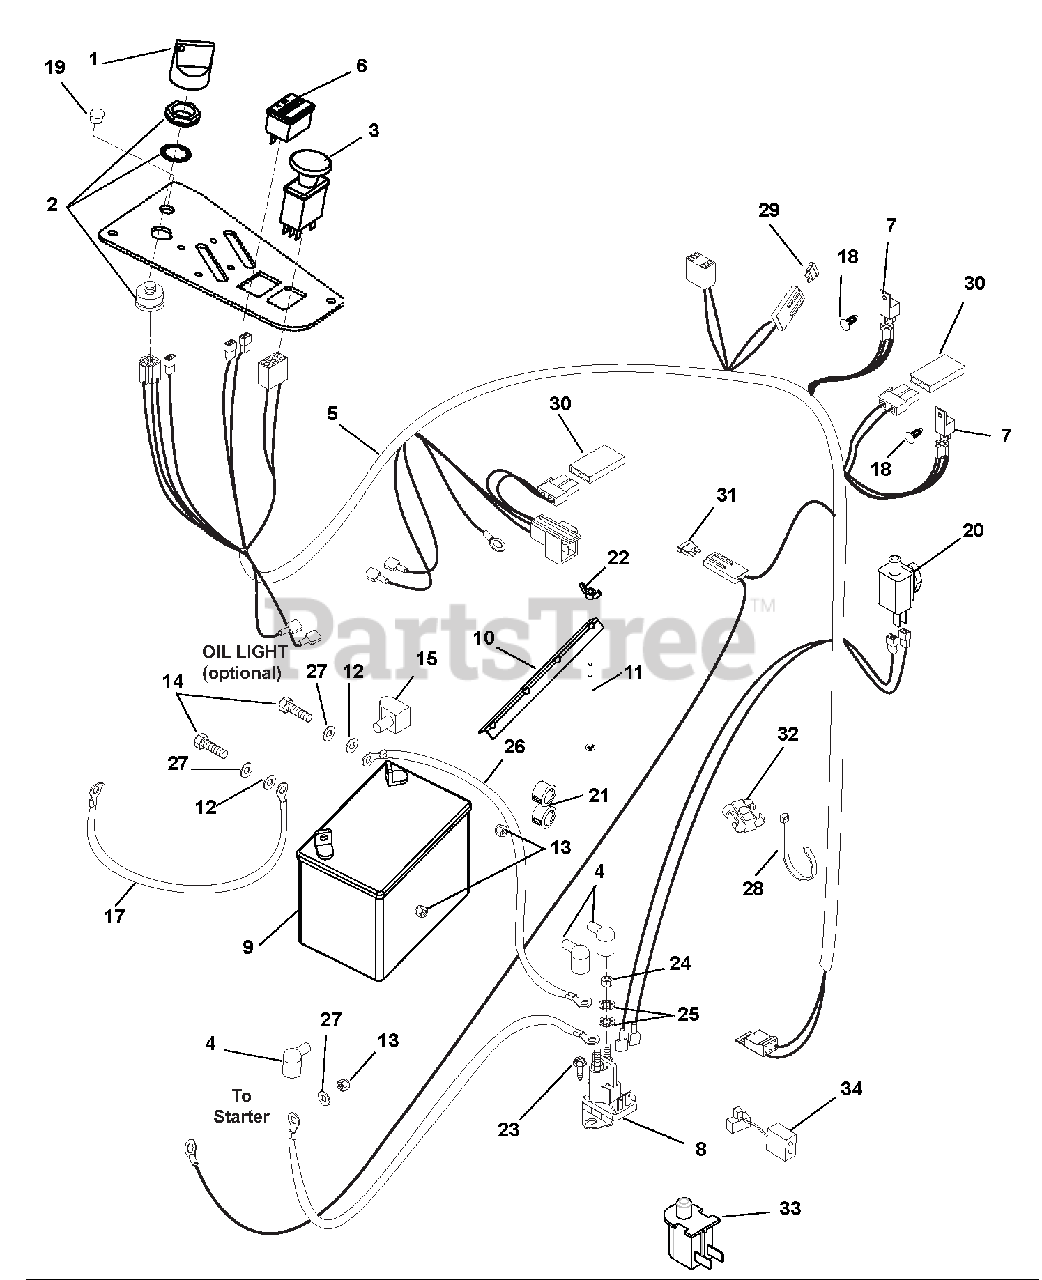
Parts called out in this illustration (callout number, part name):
1	KEY, W/ SHIELD
2	SWITCH, IGNITION
3	SWITCH, CLUTCH
4	BOOT, BATTERY TERMINAL-RED
5	HARNESS - WIRE
6	METER, HOUR W/MAINTENANCE
7	RELAY,SEALED W/DIODE
8	SOLENOID, HP RTV
9	BATTERY, 300 CCA 10U1L
10	HOLD DOWN
11	BLT-RDHDSQNK .25-20X7.50 GR2YZ
12	@WSHR-FL-STL.281X.62X.065 YWZC
13	@NUT-HEX .25-20 YWZC
14	@BLT-HEX .25-20X.75 GR5 YWZC
15	INSULATOR
16	CABLE-POSITIVE BATTERY 9.00"
17	CABLE-NEGATIVE BATTERY 24.00"
18	RIVET, .25 NYLON PANEL
19	PLUG-HOLE .50 DIA
20	SWITCH, SINGLE POLE N.O.
21	BUSH, PANEL SNAP .687X.875X.56
22	NUT-LK WING .250-20 YWZC
23	@SCR-TAP .25-20X.50 HWH TR YWZ
24	NUT-JAM .31-24 YWZC
25	@WSHR-LK-EXT.326X.599X.031YWZC
26	CABLE, STARTER .31X23.00X.31
27	@WSHR-LK .25X.062 REG YWZC
28	CABLE TIE LG 5-1/2
29	FUSE 20AMP
30	DIODE, CONNECTOR SHELL
31	FUSE-25 AMP ATC TYPE
32	CLIP,T,.31-.38,
33	SWITCH- SNAP MTG N.O.
34	HARNESS ADAPTER, CLUTCH
